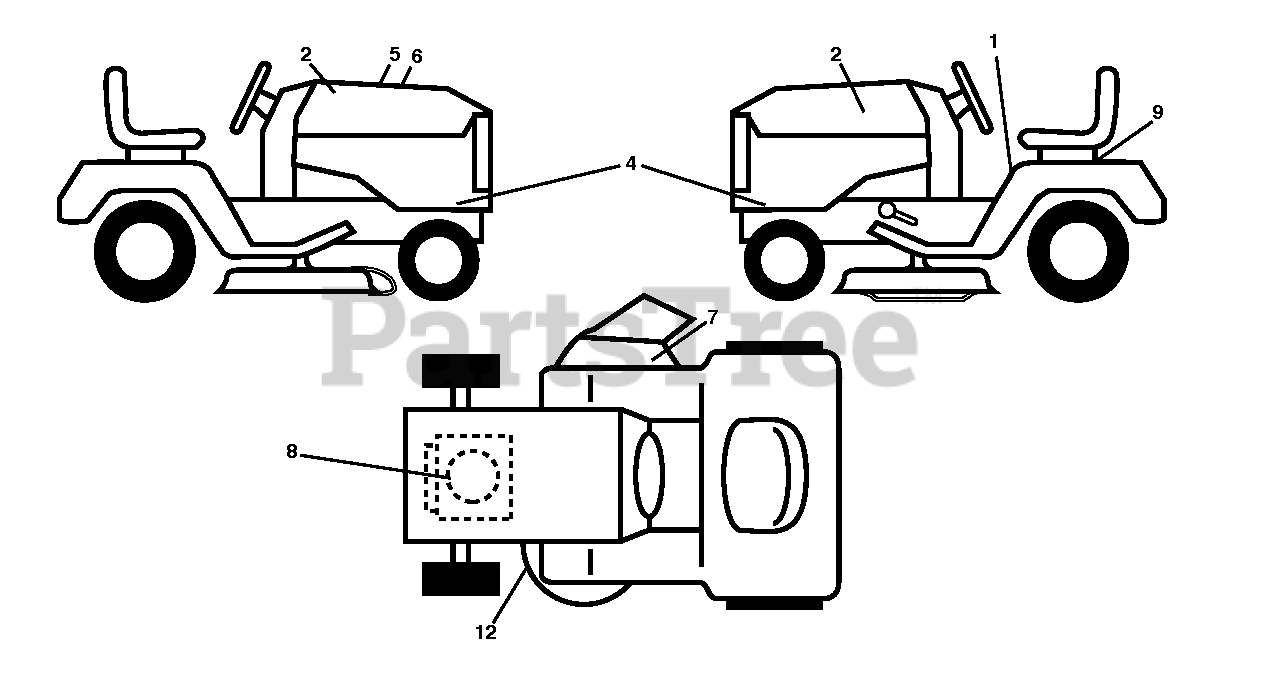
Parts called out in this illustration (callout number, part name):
1	DECAL.FENDER.WARNING.ENGLISH
2	RP.DECAL.BADGE.170MM.TEXTLOGO
4	DECAL SIDEPANEL
5	DECAL.WARNING.CUST.RESP.E85.
6	DECAL.RPL.BSM33.INTK.TLW.42
7	DECAL, DECK DEFLECTOR, WARNING
8	DECAL.ENG.BS.18.5INTK.381713
9	DECAL BTRY SYMBOLS
12	DECAL.V-BELT.SCH.42/46"MEC/ELE
